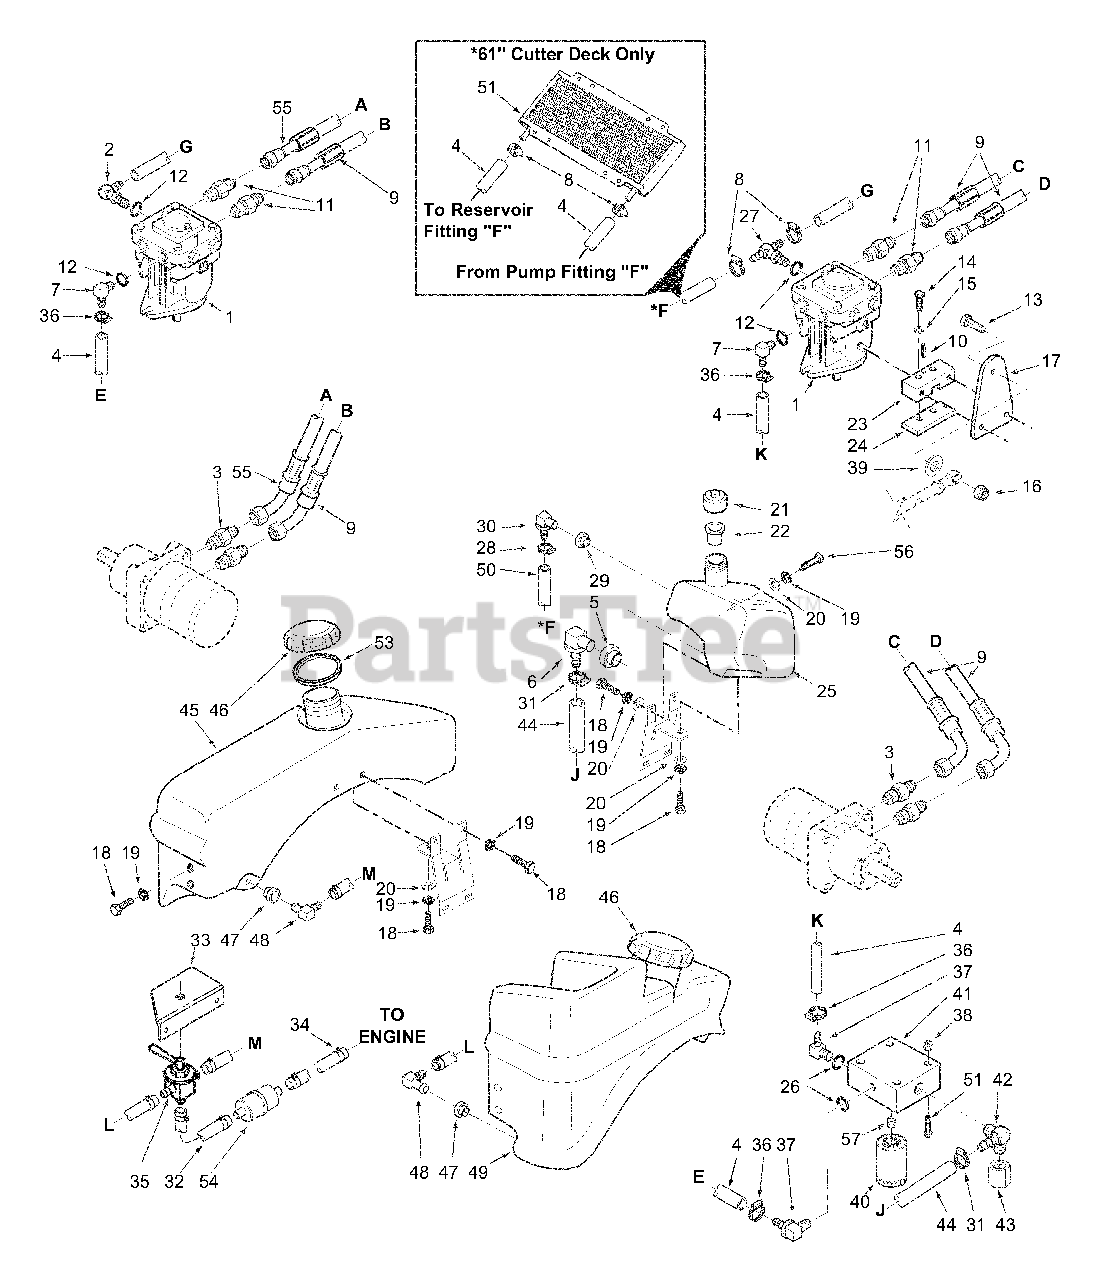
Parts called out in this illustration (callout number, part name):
1	Pump, BDP-10A-316 (L.H.)
2	Elbow, 90 Degree 9/16 O-Ring x 3/8 Hose
3	Fitting, 1/2" JIC x 5/8 O-Ring
4	Hose, 3/8 Pushlock (Specify length)
5	Bushing
6	Fitting
7	Elbow, 90 Degree 9/16 O-Ring x 3/8 Hose
8	Hose Clamp, .69 Dia.
9	Hose Assembly
10	Roll Pin
11	Fitting, 1/2" JIC x 1/2" O-Ring
12	O-Ring
13	Bolt, Hex Head 3/8-16 x 1-1/2"
14	Bolt, Hex Head 1/4-20 x 1-1/4"
15	Lockwasher
16	Nut, Elastic Stop 3/8-16
17	Control Lever
18	Bolt, Hex Head 5/16-18 x 3/4"
19	Lockwasher, 5/16
20	Flatwasher, 5/16-.375 x .875 x .083
21	Cap, Hydraulic Tank
22	Insert, Filler Neck
23	Control Block
24	Clamp Plate
25	Hydraulic Tank Assembly w/fittings
26	O-Ring
27	Tee Fitting, O-Ring to Barb
28	Clamp, .69 Max. / .25 Min. Dia.
29	Bushing
30	Elbow, 0.38 Hose
32	Fuel Hose, 1/4 ID
33	Bracket Fuel Valve
34	Clamp, Fuel Hose 1/4 Hose ID
35	Valve, Fuel Shutoff
36	Clamp, .69 Max. / .25 Min. Dia.
37	Elbow, 1/4 NTP x 3/8 Hose Barb
38	Nut, Serr. Flange 5/16-18
39	Flatwasher, 3/8-.391 x .938 x .105
40	Oil Filter
41	Filter Head Assembly
42	Fitting, Tee Special
43	Cap, 3/4-16 JIC
44	Hose, Filter Inlet
45	Fuel Tank RH
46	Cap, Fuel Tank
47	Tank Bushing
48	Elbow, 90 Degree
49	Fuel Tank LH
50	Hose, 3/8 Pushlock 15" Long
51	Cooler, Transmission (61A Only)
53	Gasket, Gas Tank Cap
54	Fuel Filter
55	Hose Assembly
56	Bolt, Hec Head 5/16-18 x 1-1/2
57	Nipple, Oil Filter 1.0-12 UNF-2A x 1-1/4"
